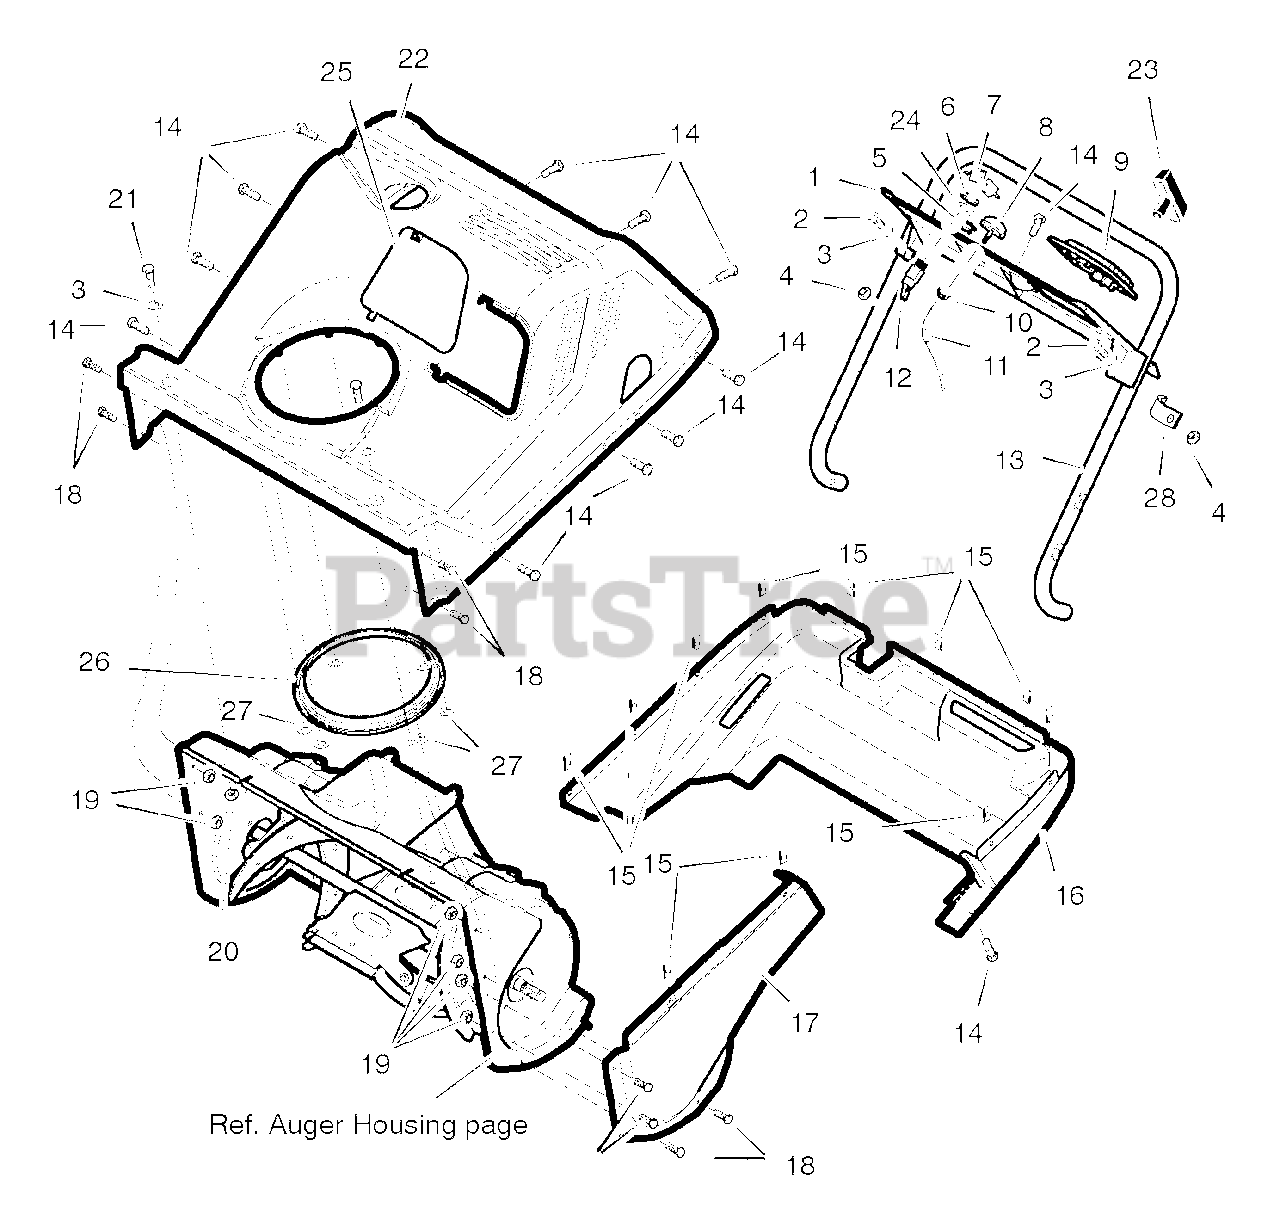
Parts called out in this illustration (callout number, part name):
1	Panel, Control
2	Screw 1/4-20 x 1.25
3	Washer
4	Nut, 1/4-20
5	Bushing, Chute Crank
6	Nut, 5/8-32
7	Keys & Ring, Starter
8	Bulb, Fuel Primer *
9	Panel, Cover Access
10	Nut, Keps 1/4-20
11	Hose, Primer 9.5"
12	Switch, Ignition
13	Handle, Lower
14	Screw 1/4-14 x .75
15	J-Nut 1/4-10
16	Cover, Bottom
17	Cover, Belt
18	Screw 10-24 x .5
19	Locknut, Hex 10-24
20	Locknut, Hex 1/4-20
21	Screw 1/4-20 x .63
22	Cover, Top
23	Knob, Standard Recoil *
24	Washer
25	Cover, Oil Access
26	Gasket, Chute Ring
27	Nut, Push
28	Clamp, Cable
